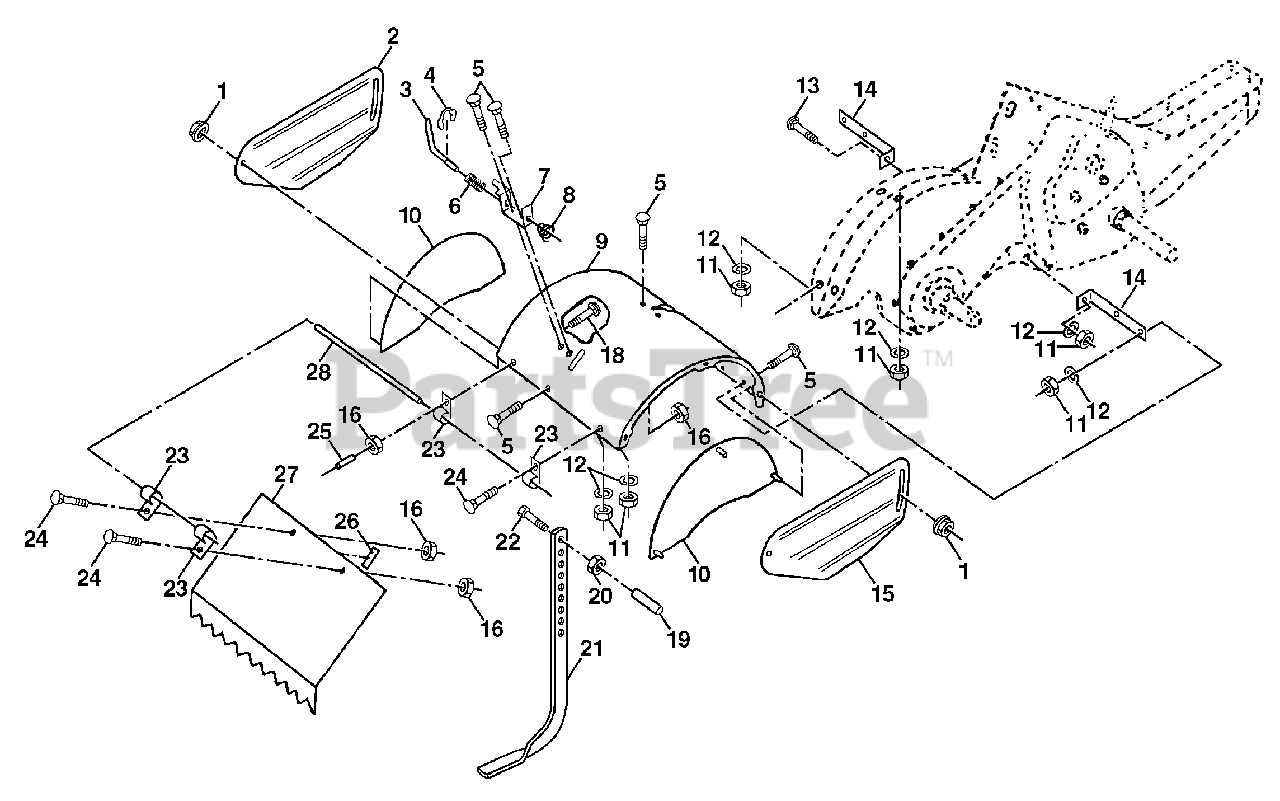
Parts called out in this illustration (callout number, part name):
1	Nut, Flange 5/16-18
2	Shield, Side, Outer L. H.
3	Pin, Stake, Depth
4	Ring, Klip
5	Bolt, Carriage 5/16-18 x 3/4 Gr 5
7	Bracket, Latch
8	Spring, Depth Stake
9	Shield, Tine
10	Shield, Side
11	Nut, Hex 5/16-18
12	Washer, Lock 5/16
13	Bolt, Carriage 5/16-18 x 1-1/4
14	Bracket, Shield Tine
15	Shield, Side, Outer R.H.
16	Nut, Keps Hex 1/4-20
18	Bolt, Carriage 1/4-20 x 1-1/4 Gr. 5
20	Nut, Hex 3/8-16
21	Stake, Depth
22	Bolt, Hex 3/8-16 x 2
24	Bolt, Carriage 1/4-20 x 1/2 Gr. 5
25	Cap, Vinyl
26	Pad, Idler
27	Shield, Leveling
28	Pin, Hinge
